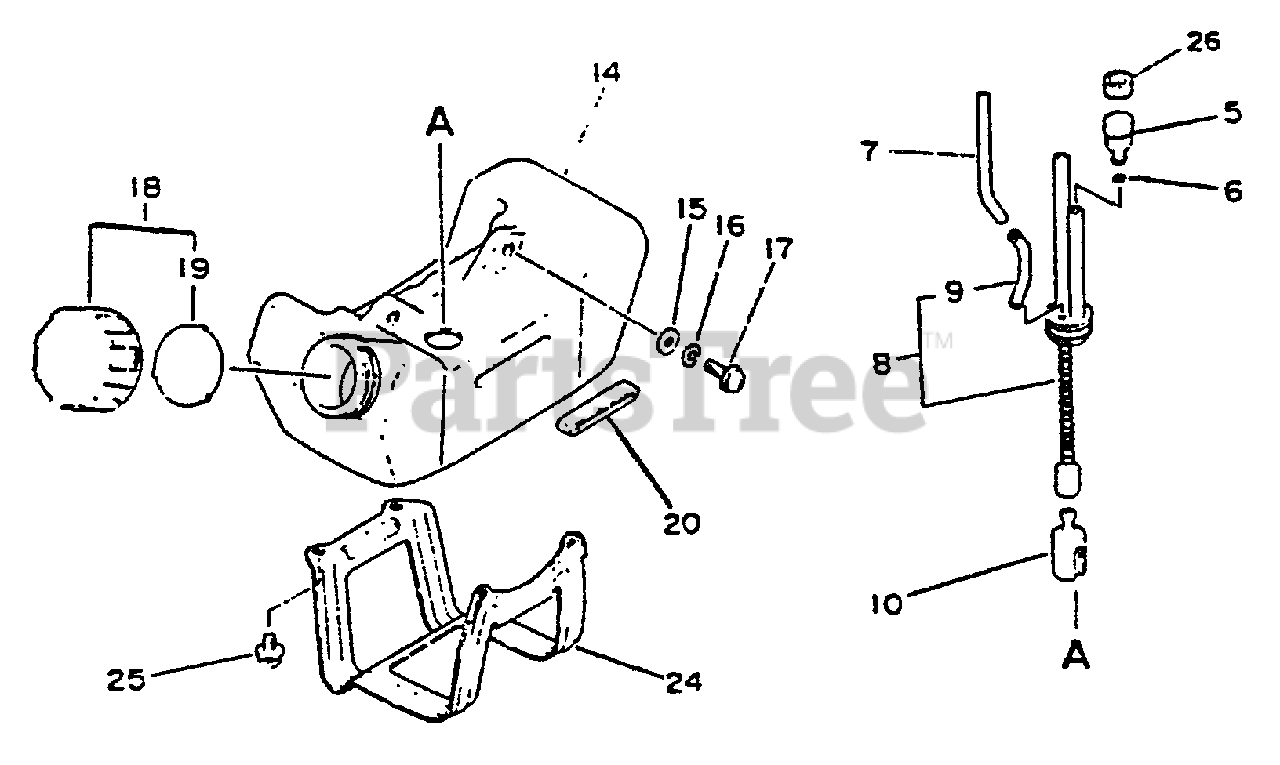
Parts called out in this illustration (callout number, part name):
5	VENT ASSY
7	PIPE, FUEL 3×6×75 CLEAR
8	PIPE KIT, FUEL
9	CONNECTOR, PIPE
10	FILTER, FUEL
14	TANK, FUEL
15	WASHER 5.5×12×0.8
16	WASHER 5.5×12×0.8
17	SCREW 5×16
18	CAP ASSY
19	GASKET, FUEL CAP
20	CUSHION, FUEL TANK
24	GUARD, FUEL TANK
25	SCREW 5×10
26	HOLDER, VENT
